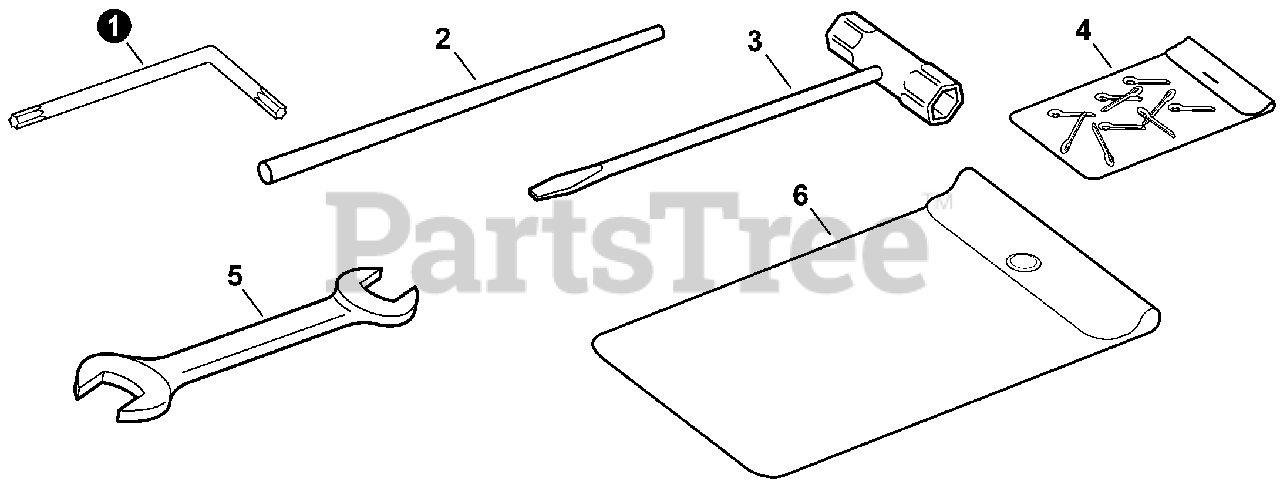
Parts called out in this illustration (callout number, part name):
1	WRENCH, ALLEN T27 80×30
2	TOOL, LOCKING 5×120 MM
3	T-WRENCH 17×19 L200
4	PIN, COTTER 2×22
5	SPANNER 8×10
6	BAG, TOOL
